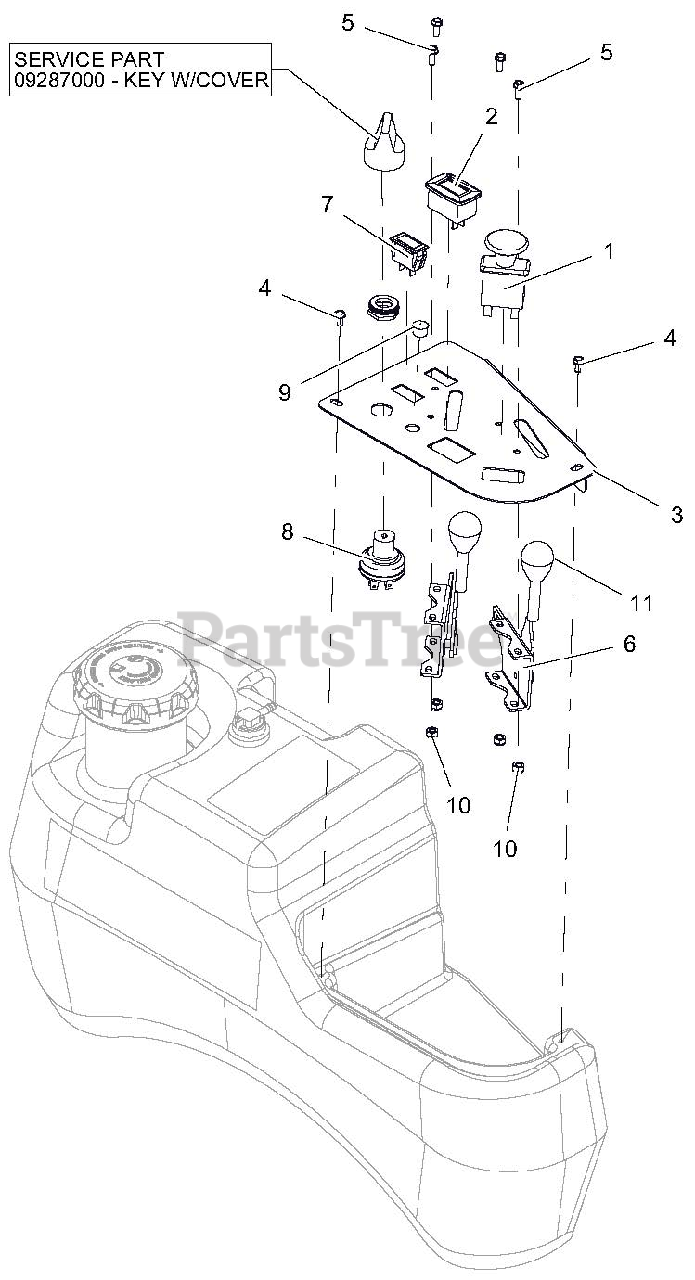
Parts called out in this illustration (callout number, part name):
1	SWITCH, CLUTCH
2	METER, HOUR W/MAINTENANCE
3	PANEL, CONTROL - PROTURN 100 (BLACK)
4	SCR-MCH 10-24X.38 HWHSTAINLESS
5	@SCR-MCH 10-24X.50 HWH YWZC
6	CABLE, THROTTLE
7	LIGHT, INDICATOR
8	SWITCH, IGNITION
9	PLUG, HOLE .50 DIA
10	NUT-LK-NYL #10-24 YWZC
11	KNOB-CONTROL-BLACK .38-16X.50
12	KEY W/COVER
